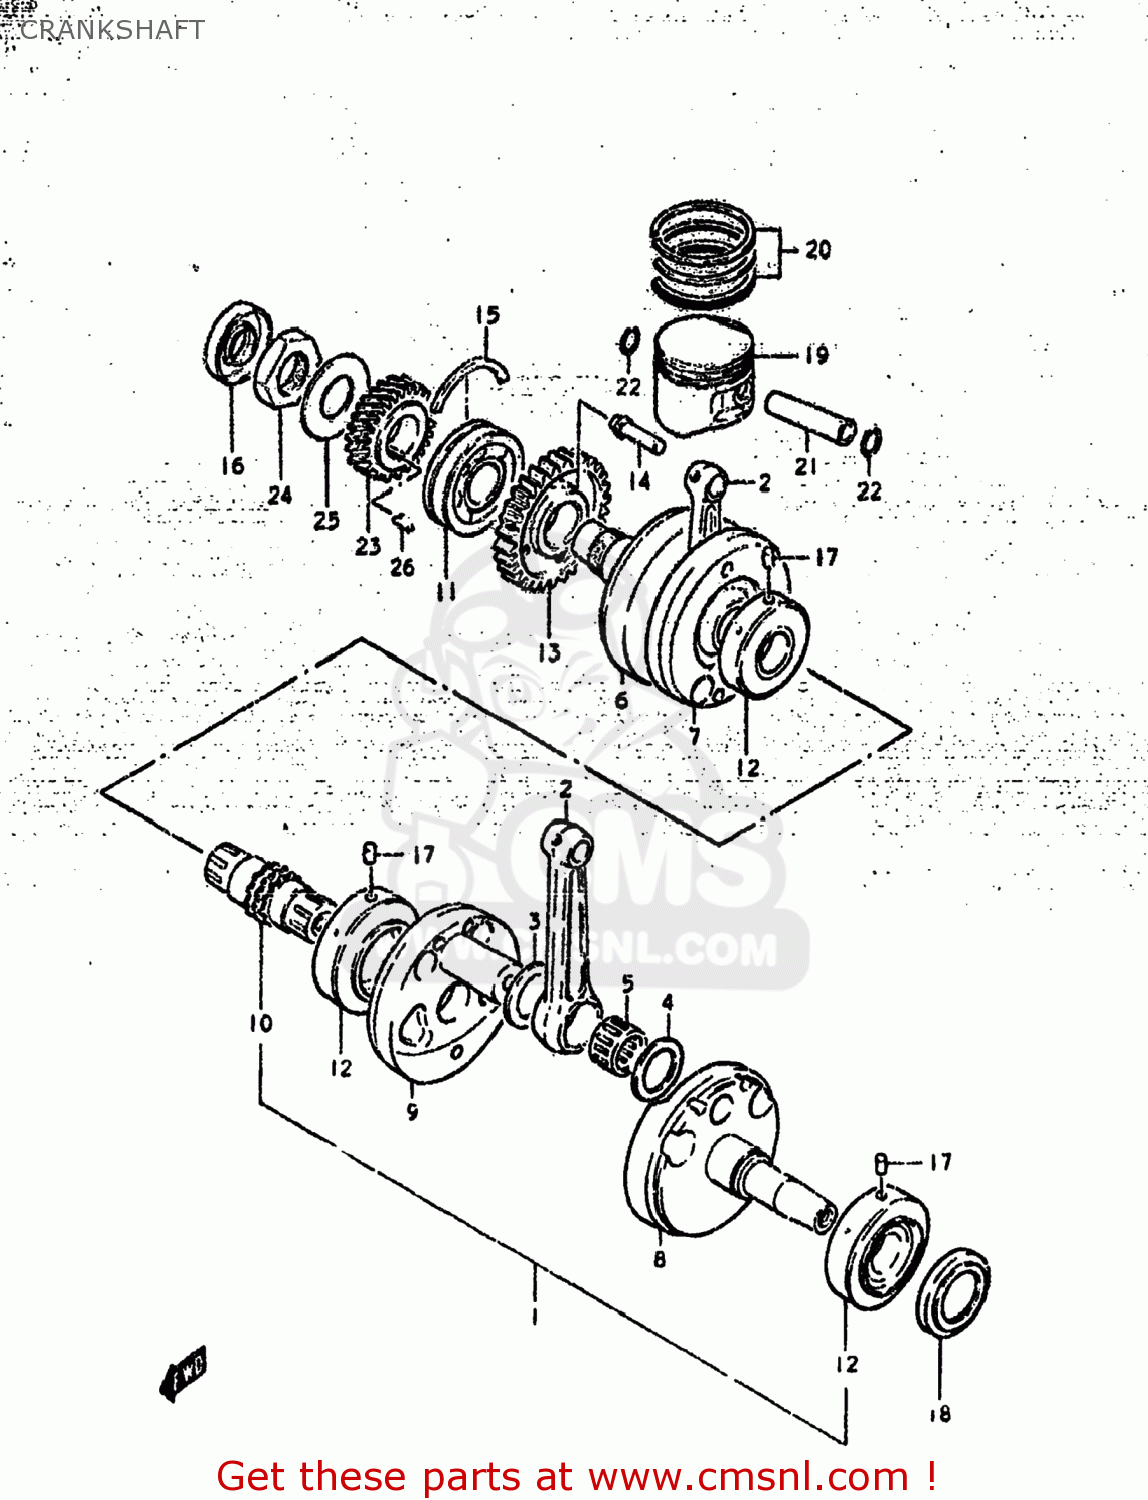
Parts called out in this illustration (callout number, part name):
1	CRANKSHAFT ASSEMBLY
2	ROD,CONNECTING
3	WASHER (28X48X2)
4	WASHER(28X48X1)
5	BEARING(28X38X19.8)
6	CRANKSHAFT
7	WEB,CRANK
8	CRANKSHAFT,LEFT
9	WEB,CRANK
10	SHAFT,TIMING CHAIN DRIVE
11	BEARING(30X72X19)
12	BEARING
13	GEAR,CRANK BALANCER DRIVE
14	PIN
15	C RING
16	SEAL,OIL(25X47X8)
17	PIN
18	OIL SEAL
19	PISTON (67.00MM)
20	RING SET,PISTON
21	PIN,PISTON
22	CIRCLIP
23	GEAR,PRIMARY DRIVE
24	NUT
25	WASHER
26	KEY
